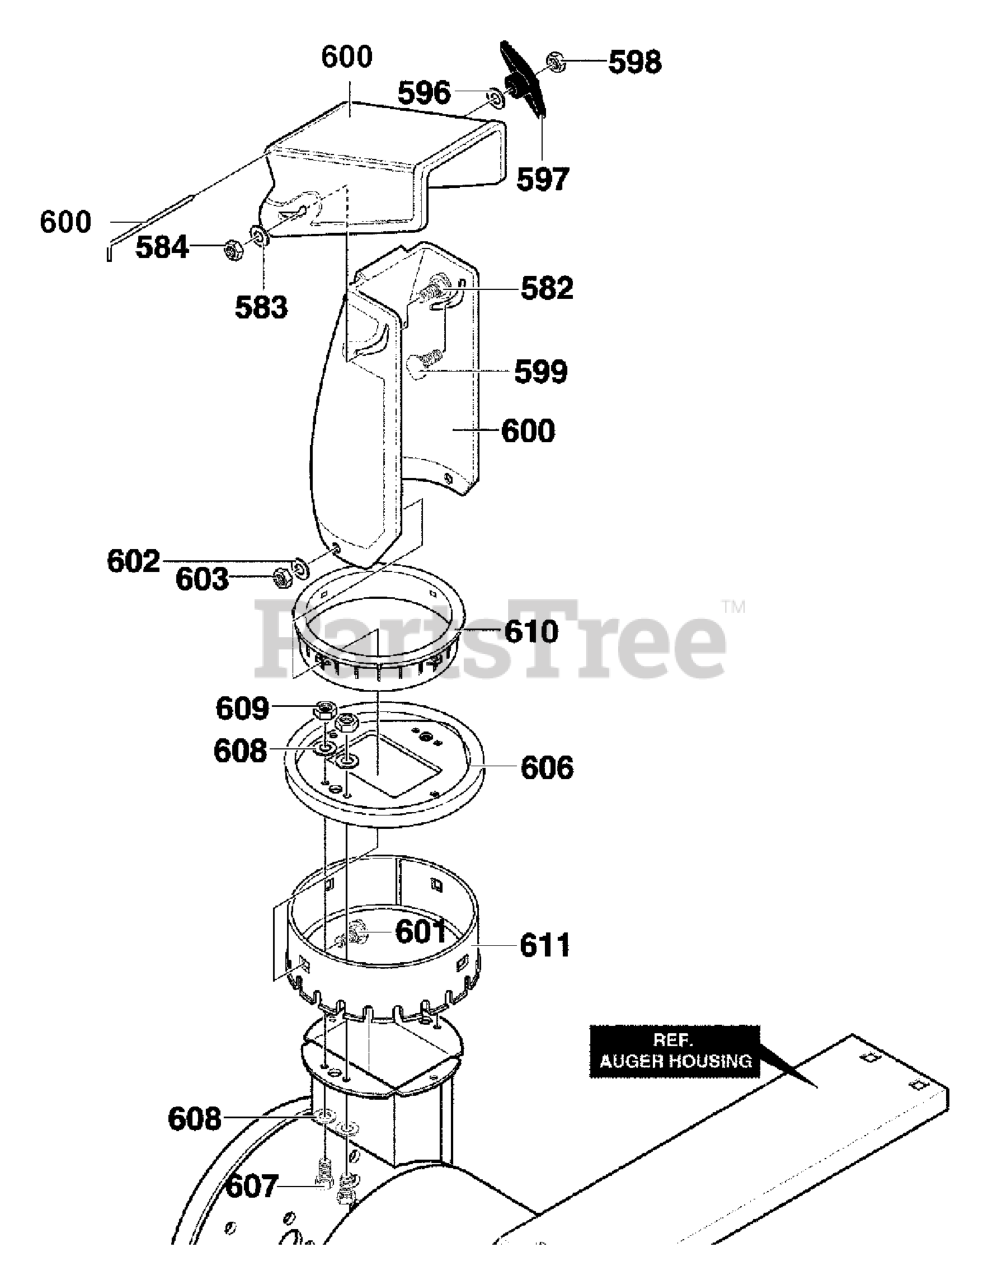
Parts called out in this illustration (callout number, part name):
582	SCREW, 5/16-18 x 0.75
583	WASHER, FLAT .349X.69X.066
584	NUT, 5/16-18 REGHEXCTRLK
596	WASHER, FLAT .349X.69X.066
597	KNOB, T 3.00
598	NUT, 5/16-18 REGHEX
599	BOLT, 5/16-18X1.25 CARR.
600	CHUTE ASSEMBLY
601	BOLT, 5/16-18 X1.00
602	WASHER, FLAT .349 X .69 X .066
603	NUT, 5/16-18 HEXNYL
606	CHUTE COLLAR
607	SCREW, 1/4-20 X .75
608	WASHER, FLAT .281X.63X.065
609	NUT, 1/4-20 HEX NYLOCK
610	RETAINER RING INNER
611	RETAINER RING OUTER
